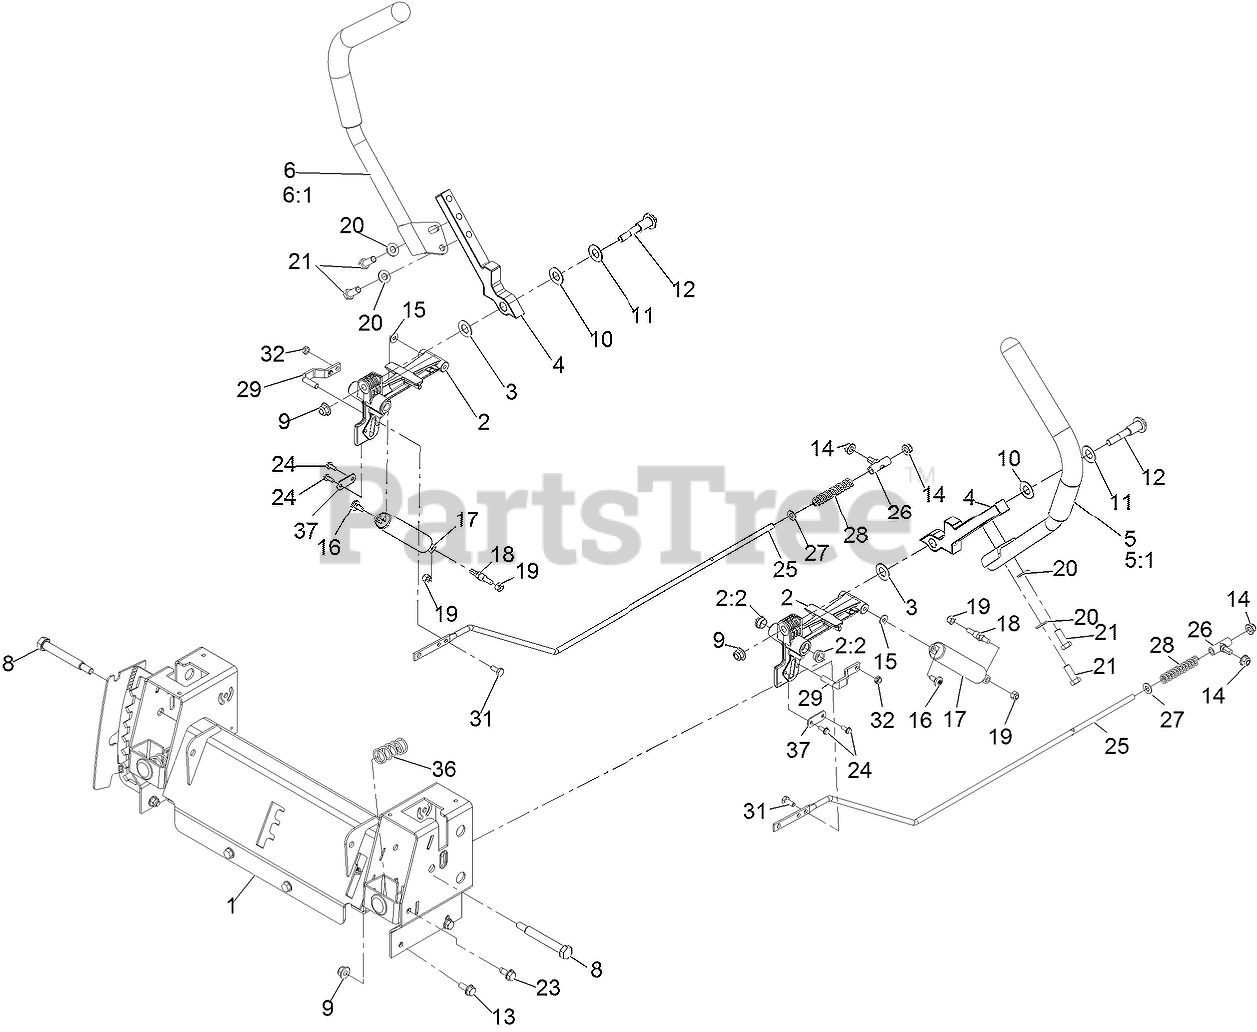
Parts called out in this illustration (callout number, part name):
1	CONTROL-BOX
2	ACTUATOR ARM ASM
2:2	BUSHING-FLANGE
3	WASHER-NYLON
4	ARM-CONTROL
5	HANDLE-CONTROL, LH
6	HANDLE-CONTROL, RH
8	BOLT-PIVOT
9	NUT-HF, NI
11	WASHER-BELLEVILLE
12	BOLT-PIVOT
13	SCREW-HHF
14	NUT-HF, NI
16	SCREW-SHOULDER
17	DAMPER-NON CAVITATING
18	STUD-DAMPER
19	NUT-LOCK, NI
20	WASHER-FLAT
21	SCREW-HH
23	Screw-HWH 5/16-18 X 3/4 Tf
24	SCREW-TAPTITE
25	Screw-HWH #10-24 X 1/2 Taptite
26	Rod-Hydro
27	WASHER-PLAIN
28	SPRING-RETURN, NEUTRAL
29	PIN-ROD, HYDRO
31	SCREW-HH
32	NUT-LOCK, NI
36	SPRING-RETURN
37	PLATE-STOP, HYDRO
